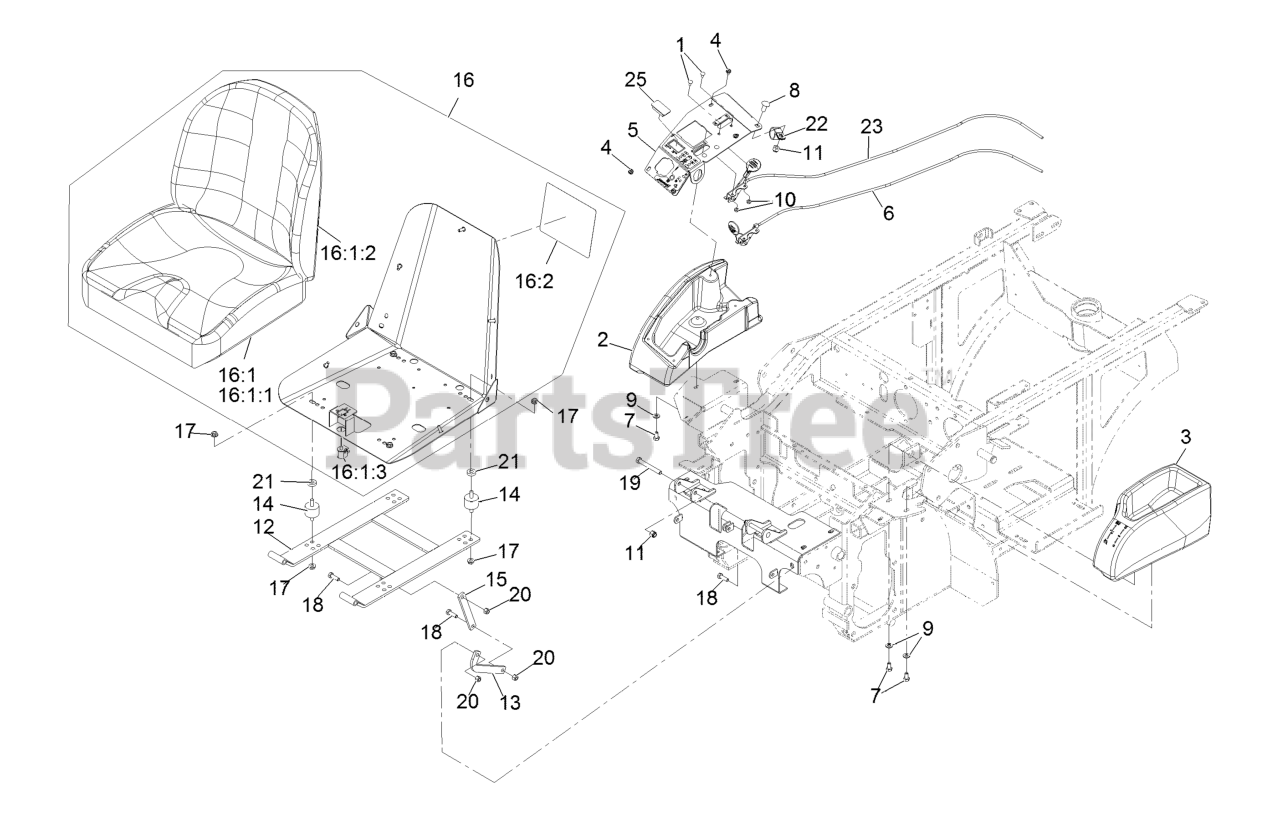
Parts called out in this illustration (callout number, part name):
1	BOLT-CARR
2	CONSOLE-RH
4	SCREW-PPH
5	CONTROL PANEL ASM
6	CABLE-THROTTLE
7	SCREW-HH
8	SCREW-CARR
9	WASHER-PLAIN
10	NUT-LOCK, NI
11	NUT-LOCK, NI
12	FRAME-SEAT
13	LINK-SEAT STOP
14	MOUNT-VIBRATION, RUBBER
15	LINK-SEAT
16:1	Asm-Seat
16:1:1	ASM-SEAT BOTTOM CUSHION
16:1:2	CUSHION,SEAT BACK
16:1:3	SWITCH-BAIL
16:2	DECAL-SERVICE AID
18	SCREW-HH
19	SCREW-CARR
20	NUT-LOCK, NI
21	SPACER
22	CLIP-LOOM
23	CABLE-CHOKE
25	PLUG-HOLE
